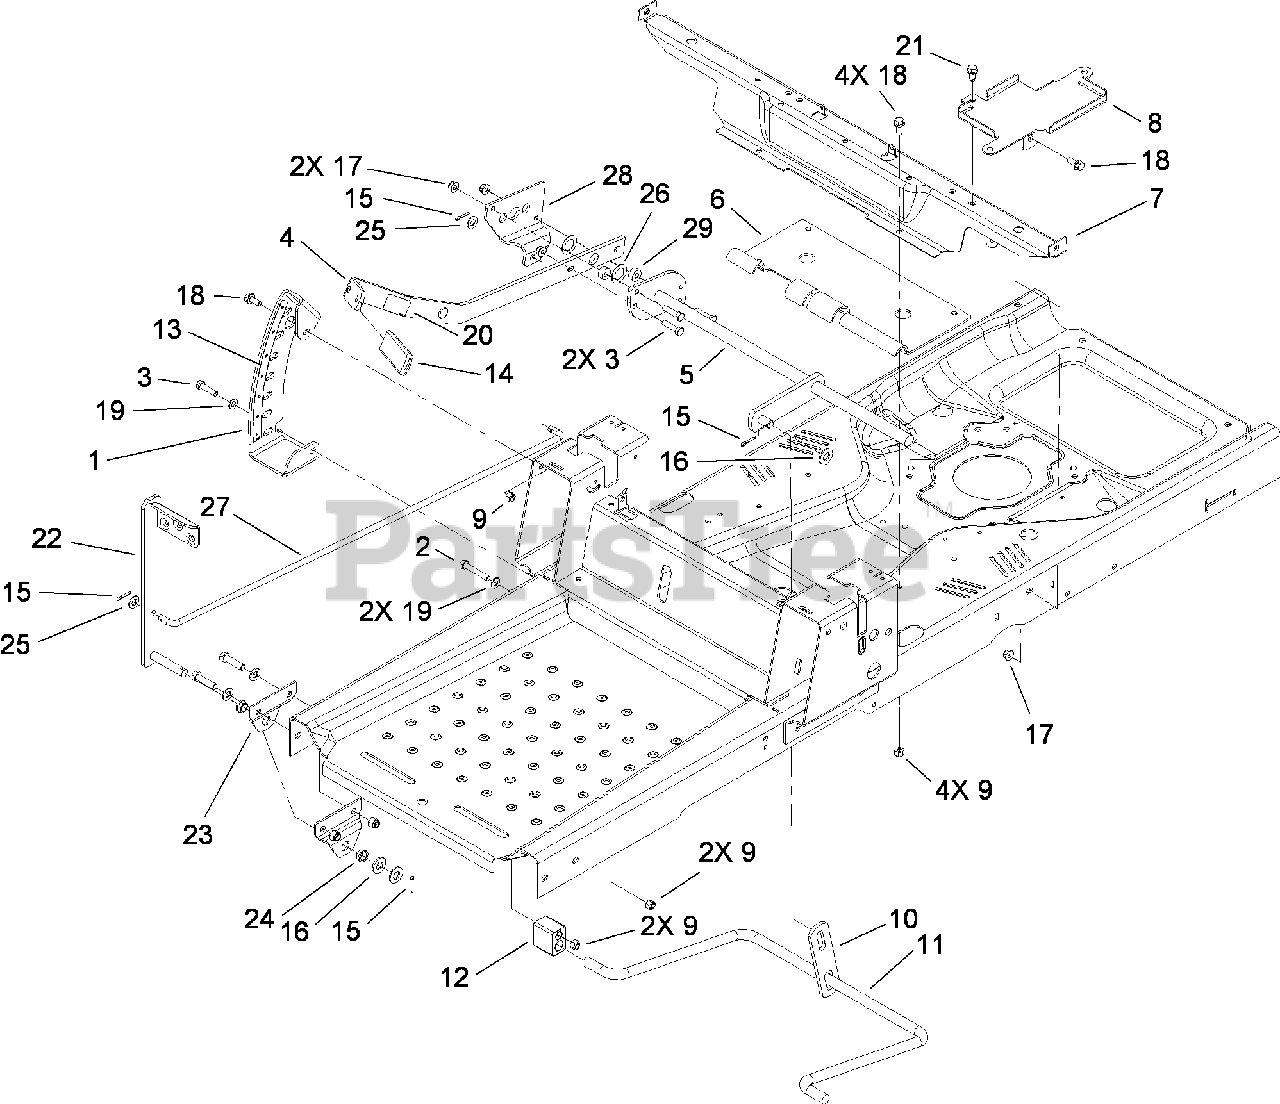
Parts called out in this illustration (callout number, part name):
2	SCREW-HH
3	SCREW-HH
4	LIFT ARM ASM
5	LIFT LEVER ASM
7	BRACKET-SEAT/PODS
8	TRAY-BATTERY
9	NUT-LOCK, NI
10	LINK-LIFT
11	ARM-LIFT, REAR
12	BLOCK-PIVOT
13	DECAL-HOC
14	GRIP-LEVER, LIFT
15	PIN-COTTER
16	WASHER-FLAT
17	NUT-FLANGE, NI
18	SCREW-HHF
19	WASHER-FLAT
20	DECAL-HOC
21	SCREW-HWH
23	BRACKET-FOOTLIFT
24	BUSHING-FLANGE
25	WASHER-FLAT
26	WASHER-THRUST
28	PLATE-FOOTLIFT
